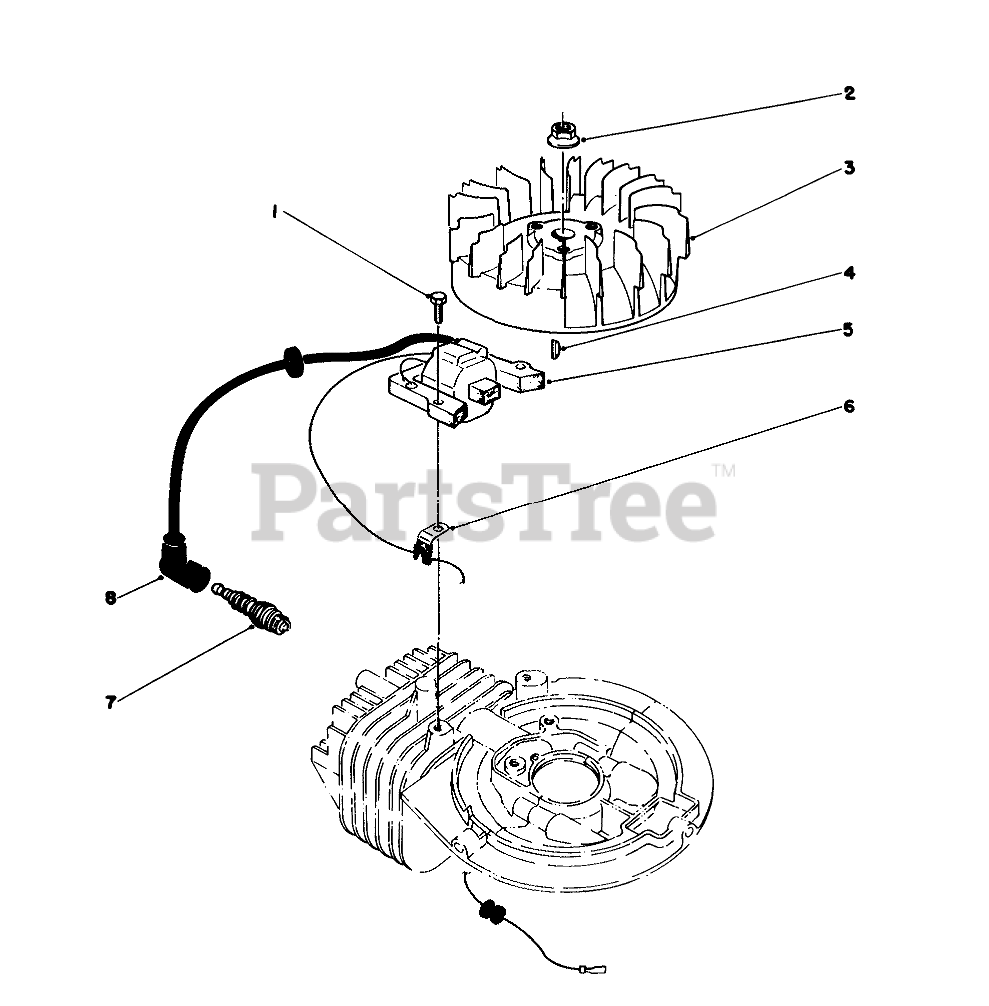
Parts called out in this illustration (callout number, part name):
1	SCREW
3	FLYWHEEL
5	COIL-MAGNETO
6	CLAMP
7	Sparkplug
8	CAP-SPARKPLUG
